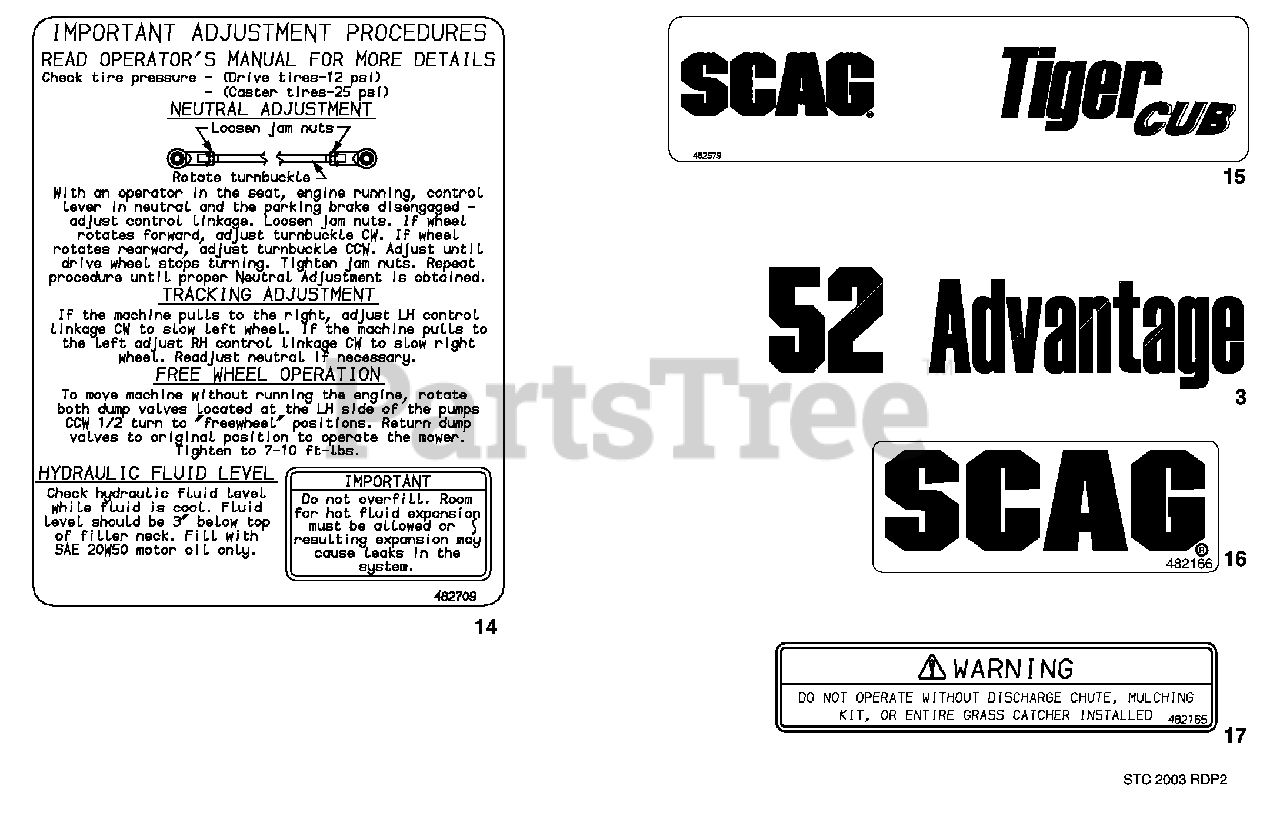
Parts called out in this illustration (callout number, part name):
3	Decal, 48A
14	Decal, Seat Support
15	Decal, Rear Bumper
16	Decal, Front Footplate
17	Decal, Discharge Chute
